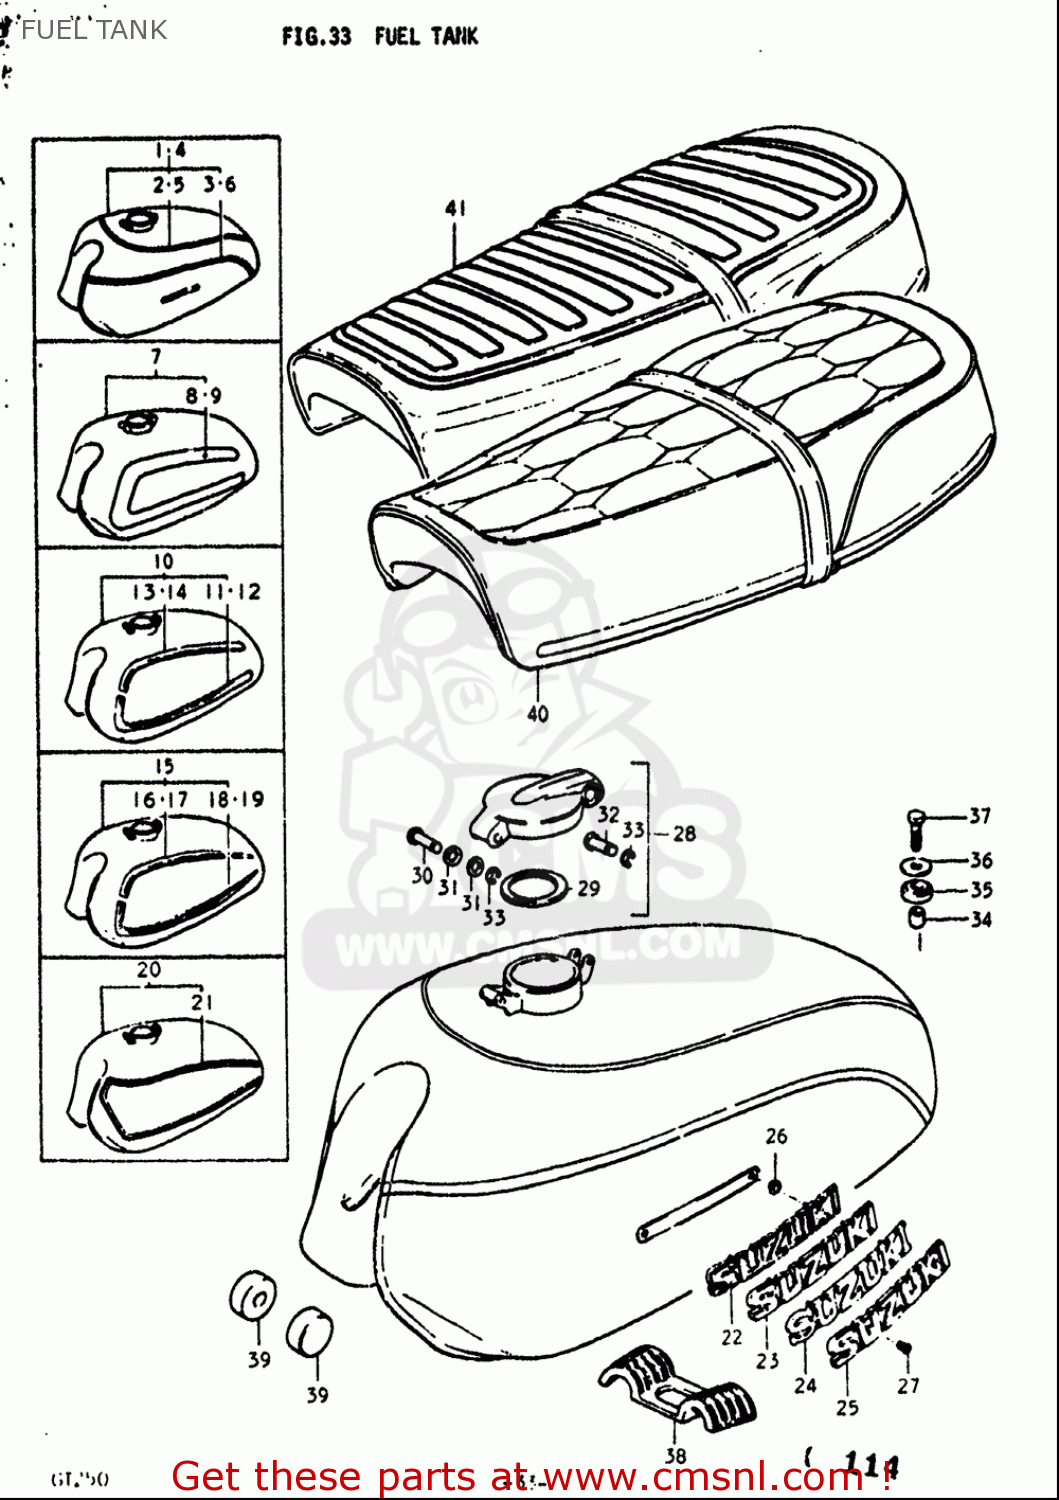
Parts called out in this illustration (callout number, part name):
25	EMBLEM,FUEL TANK
26	NUT
27	SCREW
28	CAP ASSY,FUEL TANK
29	GASKET (NAS)
31	WASHER
33	E RING
34	SPACER(8.5X12X11)
35	BUSH(12X15X20)
36	WASHER(8.5X28X1.6)
37	BOLT
39	CUSHION
